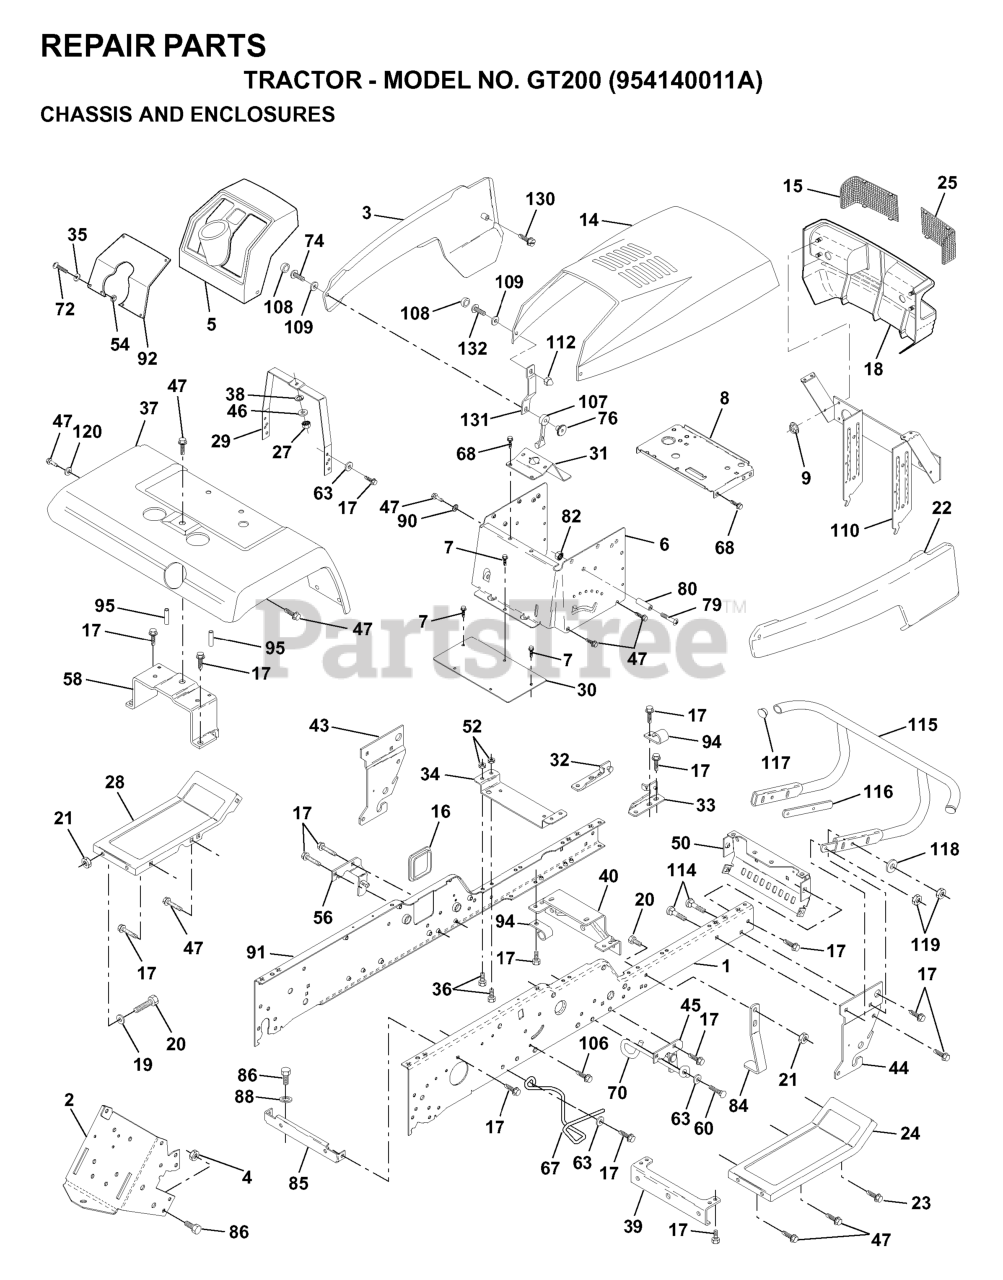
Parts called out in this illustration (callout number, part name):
1	RAIL, FRAME RH
2	DRAWBAR-GT
3	SIDE PANEL LH
4	Nut, Lock Hex 7/16 Unc
6	DASH ASS'Y LOWER
7	SCREW
8	SUPPORT, BATTERY
9	PAL NUT LT
14	HOOD ASM PNT
16	COVER ACCESS
17	SCREW
18	GRILLE.ASM.HUSQVARNA.YTGT
19	WASHER
20	BOLT
22	PANEL ASM SD RH
23	SCREW GTV
24	FOOTREST RH
25	LENS.RH.HUSQVARNA.YTGT.CL
27	NUT
28	FOOT REST LH
29	DASH SUPT YP
31	BRACE, SUPPORT STEERING
32	FRAME PIVOT BRKT ASSY LH
33	FRAME PIVOT BRKT ASSY RH
34	ENGINE SUPPORT BRKT
35	WASHER
36	BOLT.FIN.HEX.5/16-18X3/4
37	FENDER
38	LOCKWASHER
39	FRONT AXLE BRACKET
40	AXLE SUPPORT BRKT
43	FRONT SUSPENSION BRKT LH
44	FRONT SUSPENSION BRKT RH
45	BRACKET SUSP RH
46	WASHER PM
47	SCREW LT
50	BRACKET, CHASSIS FRONT
52	NUT.71038.31-18.HEX.NYLOCK
54	NUT
56	BRACKET ASM, SUSP CHASSIS
58	FENDER BRKT
60	SCREW
63	WASHER
67	BELT GUIDE
68	Screw 5/16-18 x 1/2 Hex, Self Tapping 5/16-18 x 1/2
70	BELT GUIDE
72	Screw, Machine, Truss Head 5/16-18 UNC x 3/4
74	SCREW
76	WELDNUT
79	RP SCREW
82	NUT **
84	MOWER STOP
85	BRACKET SUPPORT PNT TRANS VGT
86	BOLT
88	LOCKWASHER
90	LOCKWASHER
92	DASH PLATE
95	NUT-PUSH YT
106	SCREW
107	LATCH.HOOD.
108	SNAP CAP LT
110	PIVOT ASM GRL/HD
112	NUT
114	BOLT.3/8-14X1.25
116	BRACKET BUMPER
117	PLUG PLASTIC
118	WASHER
120	WASHER
130	Screw, SLTD Hex Hd. W/Pl Washer
131	BRACKET.SUPPORT.HOOD/PANEL.NLA
132	SCREW 10-24X3/8
